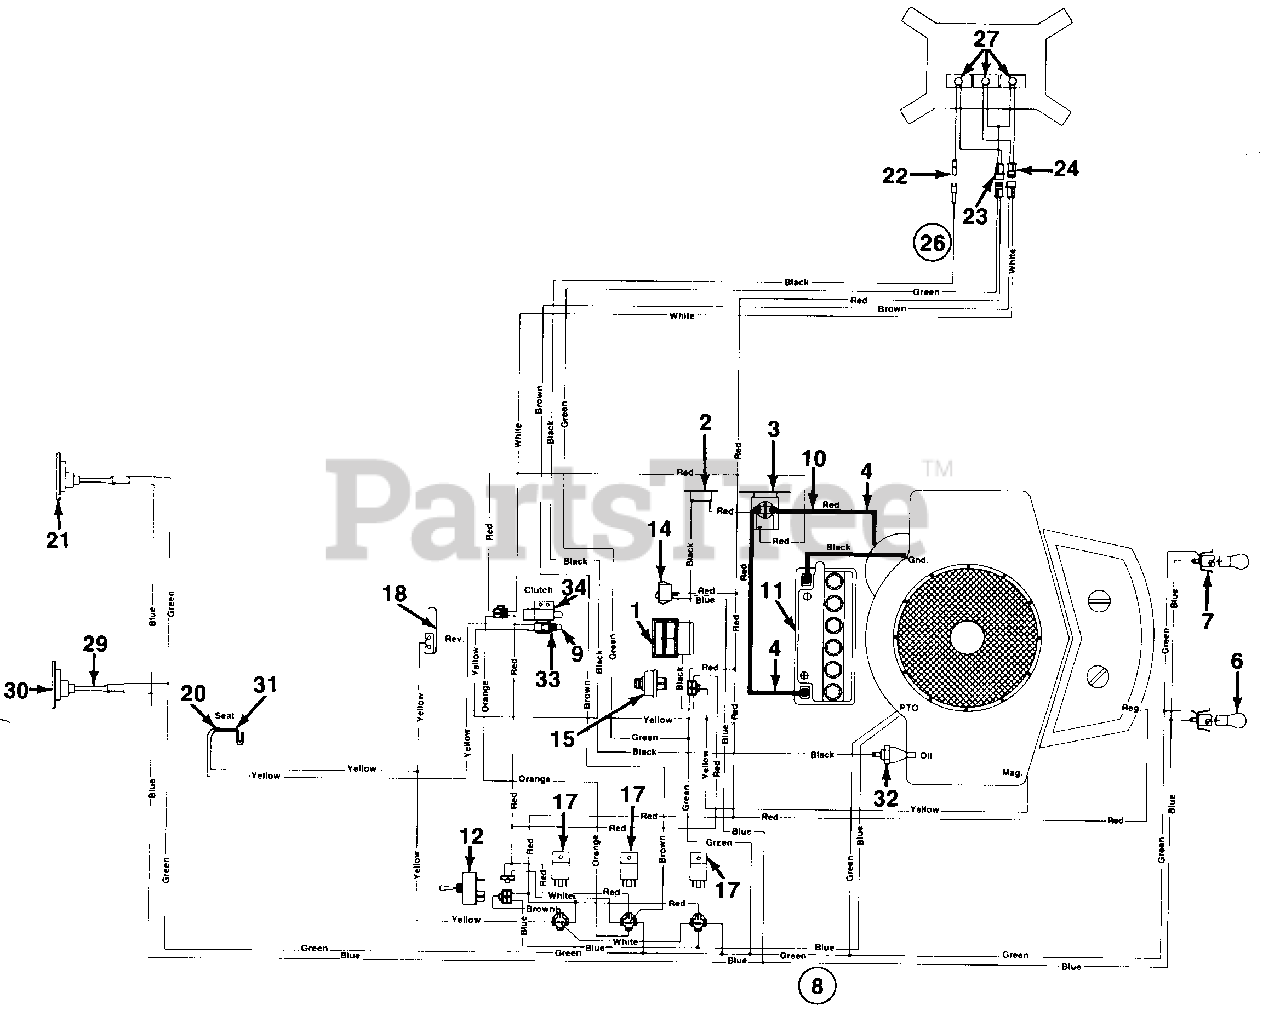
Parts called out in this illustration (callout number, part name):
1	Ammeter
2	Circuit Breaker
3	Solenoid
4	Wire
6	Bulb
7	Socket
8	Wire Harness
9	Safety Switch (Clutch)
10	6 Ga. Black Wire
11	Battery (275 Cold Crank Amps)
12	Switch (PTO)
14	Light Switch
15	Ignition Switch
17	Relay
18	Spring Lever
20	Safety Switch (Seat)
21	Taillight
22	Connector
23	Connector
24	Connector
26	Wire Harness
27	Bulb
29	Taillight Harness
31	Safety Switch (Seat)
32	Oil Pressure Switch
33	Safety Switch (Clutch)
34	Clutch Switch Mtg. Brkt.
